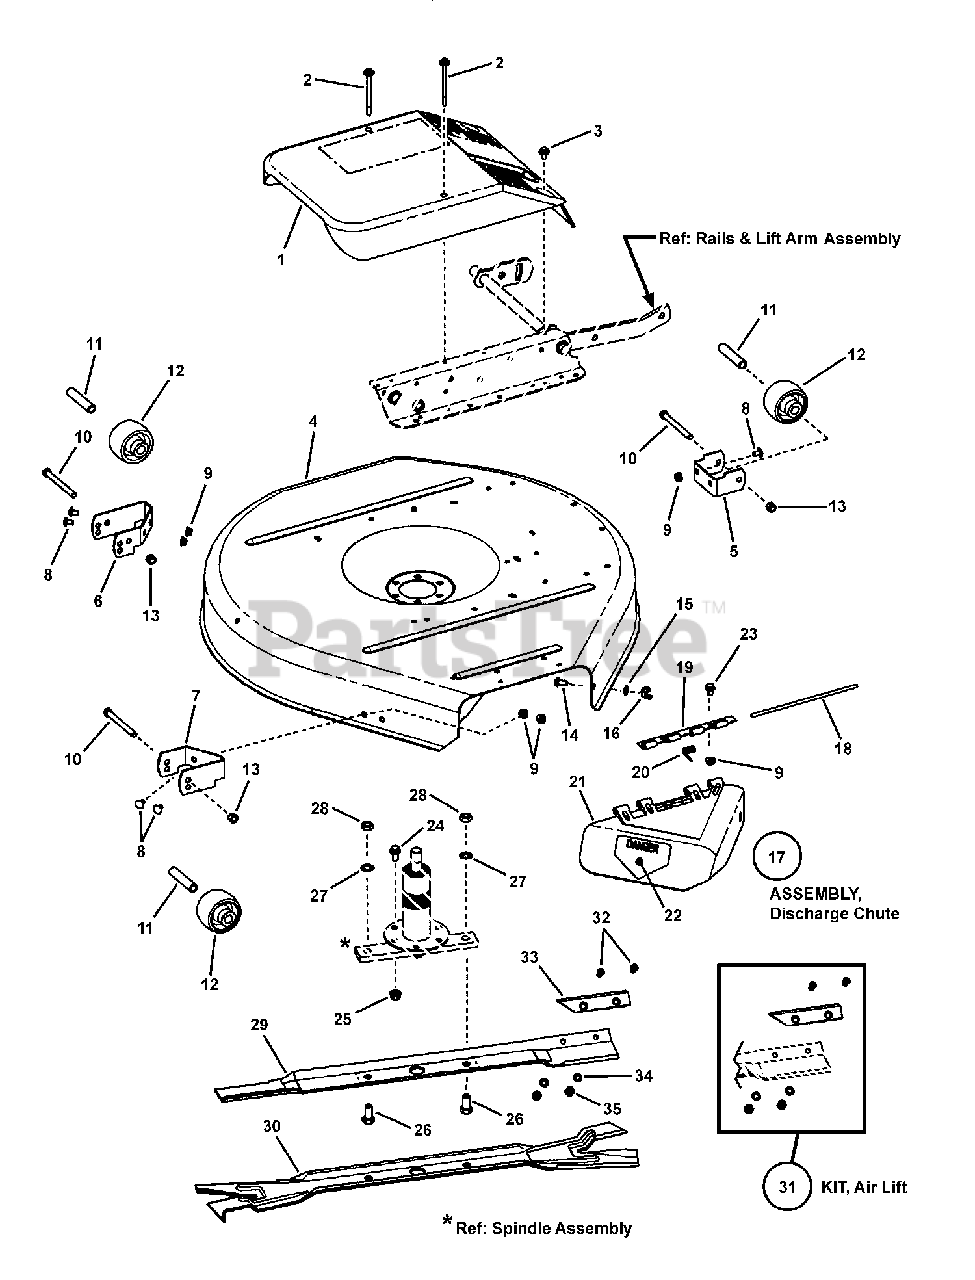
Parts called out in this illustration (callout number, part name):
1	COVER, Spindle
2	SCREW, 1/4-20 x 3-1/2" Hex Head w/Free Spinning Washer
3	SCREW, 1/4-20 x 5/8" Hex Head w/Free Spinning Washer
4	DECK, 30" Replacement (Painted deck with decals)
5	* BRACKET, Front Anti-Scalp
6	* BRACKET, Anti-Scalp, 30" L.H. Rear
7	* BRACKET, Anti-Scalp, 30" R.H. Rear
8	BOLT, 5/16-18 x 1/2" Short Neck Carriage, GR 5
9	NUT, 5/16-18 Hex Flange Lock, GR 5
10	* SCREW, 3/8-24 x 3-3/4" Hex Head Cap, GR 5
11	* SPACER
12	* WHEEL, Gage
13	* NUT, 3/8-24 Hex Center Lock, GR 5 or B
14	BOLT, 5/16-18 x 3/4" Short Neck Carriage, GR 5
15	WASHER, 5/16" Flat
16	NUT, 5/16-18 Wing
17	ASSEMBLY, 30" Deflector (Incl. items 18, 19 & 20)
18	PIN, Hinge (Straight, 8-7/8" long)
19	HINGE, Deflector (8" long)
20	SPRING, Hinge
21	DEFLECTOR, 30" Deck
22	DECAL, Danger, (Cut Finger)
23	BOLT, 5/16-18 x 5/8" Hex Flange Lock, GR 5
24	BOLT, 3/8-16 x 3/4" Hex Flange Lock
25	NUT, 3/8-16 Hex Flange Lock
26	SCREW, 1/2-20 x 1" Hex Head Cap, GR 5
27	WASHER, 1/2" Internal Tooth Lock
28	NUT, 1/2-20 Hex Jam
29	BLADE, 30"
30	BLADE, Ninja, 30"
31	KIT, Air Lift (Includes items 4 thru 7)
32	SCREW, 5/16-24 x 11/16" Oval Head Machine
33	AIR-LIFT (30" Models)
34	WASHER, 5/16" Internal Tooth Lock
35	NUT, 5/16-24 Hex
